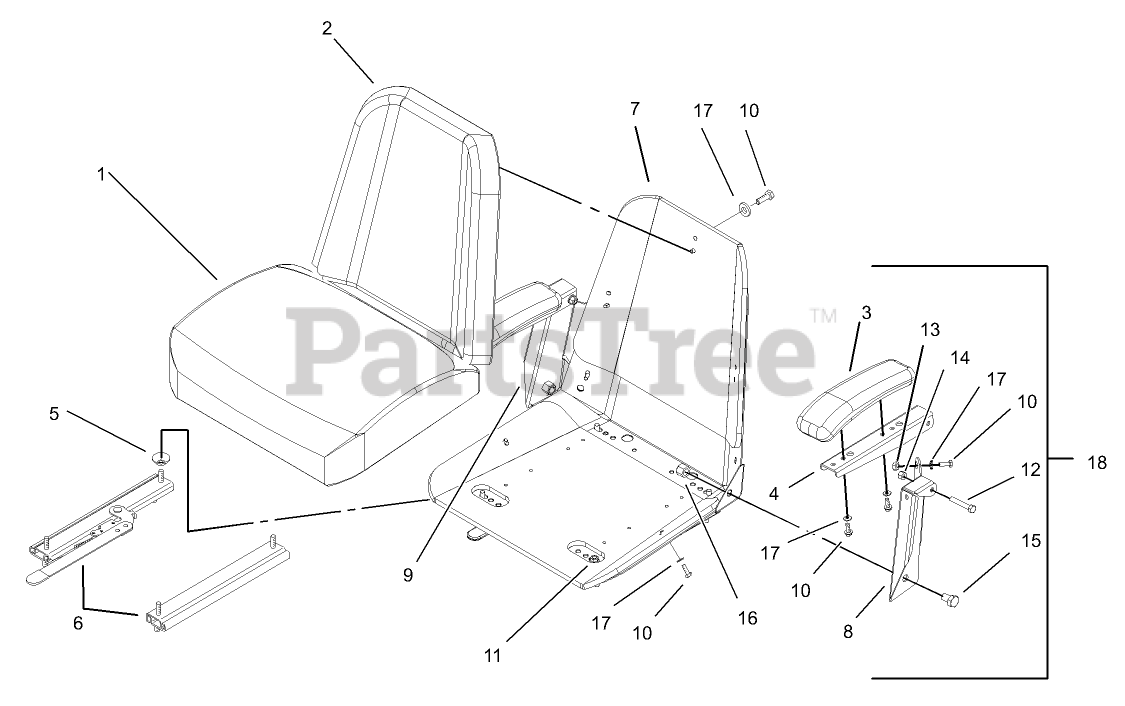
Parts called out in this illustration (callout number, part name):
1	CUSHION-SEAT, BOTTOM
2	CUSHION-SEAT, BACK
3	CUSHION-ARMREST
4	CHANNEL-ARMREST
5	SPACER-TRACK
6	TRACK-SEAT
7	FRAME-SEAT
8	Bracket-Armrest, LH
9	Bracket-Armrest, RH
10	SCREW-HH
11	NUT-HF
12	SCREW-HH
13	NUT-LOCK, NI
14	NUT-HEX, SIDE DEFORM
15	SCREW-HH
16	NUT-LOCK, NI
17	WASHER-FLAT
18	ARMREST KIT
